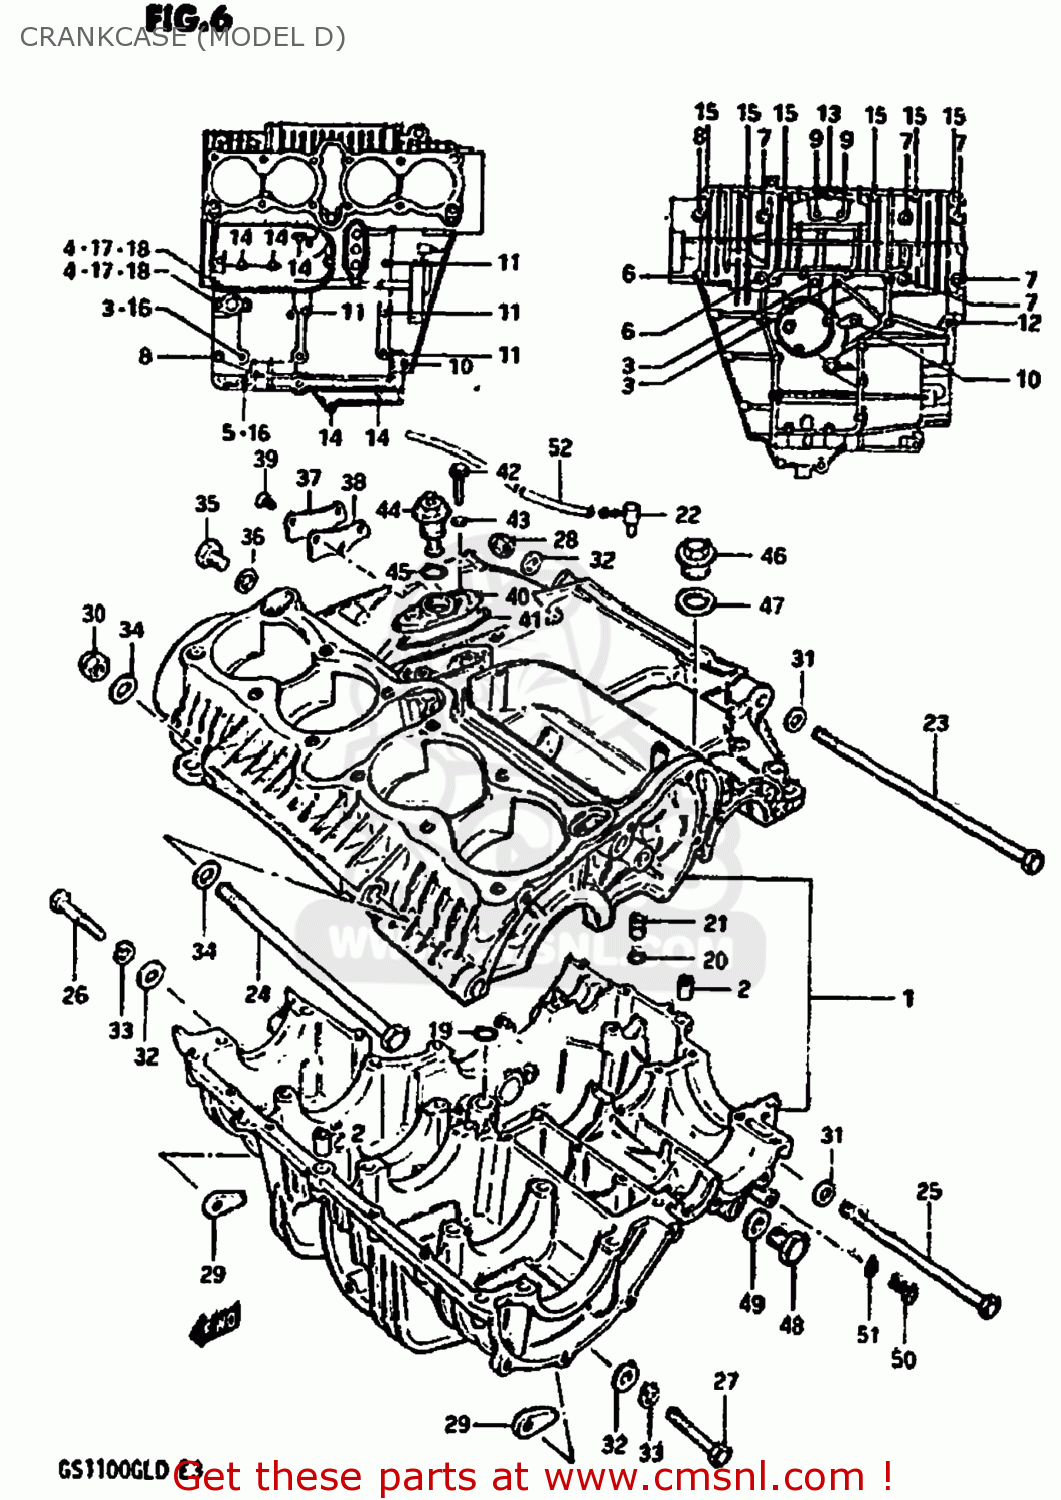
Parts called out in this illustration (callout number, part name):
1	CRANKCASE SET
2	PIN
3	BOLT
4	BOLT 8X110
5	BOLT
6	BOLT
7	BOLT (8X90)
8	BOLT (8X65)
9	BOLT 8X60
10	BOLT (6X90)
11	BOLT (6X75)
12	BOLT 6X55
13	BOLT 6X50
14	BOLT (6X45)
15	BOLT
16	NUT 8MM
17	NUT
18	GASKET 8.2X14X1 (NAS)
19	O RING(D:3.2,ID:12.9)
20	O RING(D:1.05,ID:3.1)
21	UNION
22	BPLUG,BEVEL GEAR BREATHER
23	BOLT
24	SHAFT,REAR SWING ARM
25	BOLT
26	BOLT (10X60)
27	BOLT (10X50)
28	NUT (10MM)
29	NUT
30	NUT
31	WASHER (10.5X20X3.2)
32	WASHER
33	LOCK WASHER
34	WASHER
35	PLUG (14X12)
36	GASKET(14X19.2X2) (NAS)
37	CAP,OIL GALLERY
38	GASKET,OIL GALLERY (MCA)
39	SCREW
40	HOUSING,OIL PRESSURE SWITCH
41	O RING,PRESSURE SWITCH HOUSING
42	BOLT
43	GASKET (NAS)
44	SWITCH ASSEMBLY
45	O RING(D:1.9,ID:18.8)
46	PLUG
47	GASKET
48	PLUG
49	GASKET(14X19.2X2) (NAS)
50	SCREW(6X10)
51	GASKET (NAS)
52	HOSE
